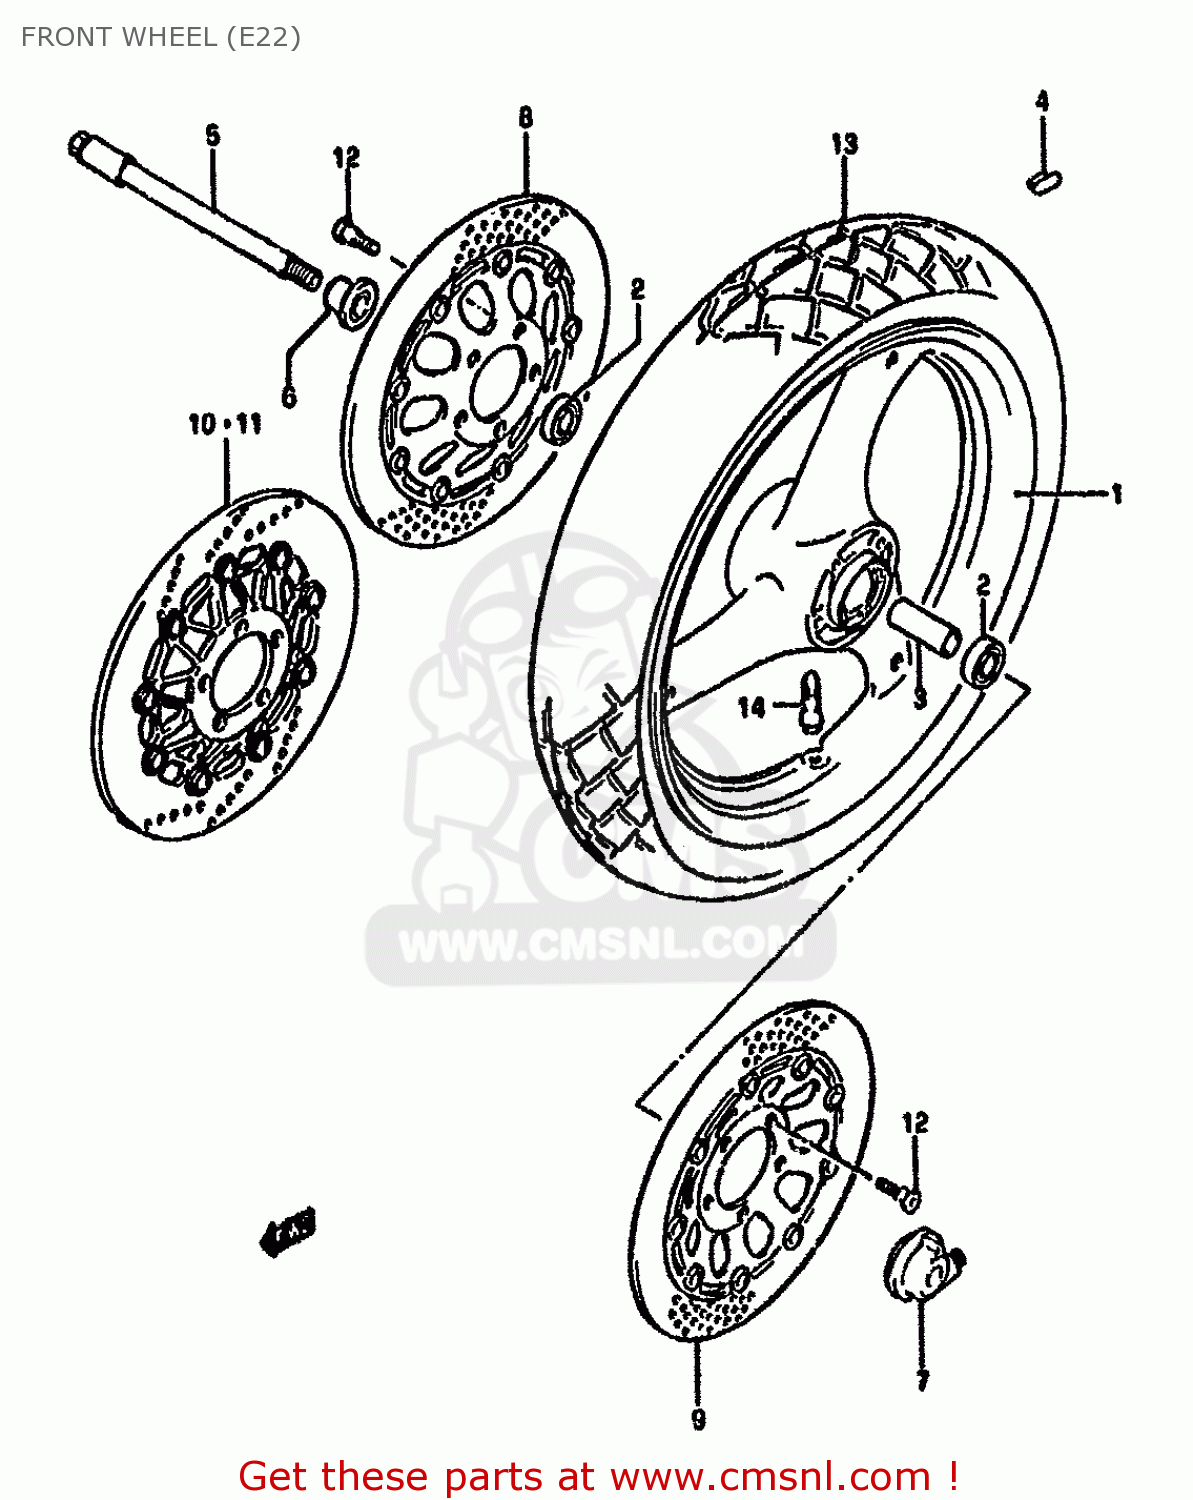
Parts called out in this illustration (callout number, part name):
1	WHEEL,FRONT (MT3.00X17) (GOLD)
2	BEARING
3	SPACER(17.5X22.5X73)
4	BALANCER,WHEEL
5	AXLE,FR
6	SPACER,FR AXLE,R
7	BOX ASSY,SPEEDOMETER GEAR
8	DISC,FR BRAKE,R
9	DISC,FRONT BRAKE LH
10	DISC,FR BRAKE,R
11	DISC,FR BRAKE,L
12	BOLT 8X33
13	TIRE,FR(110/70-17 54H)
14	VALVE ASSY,WHEEL RIM(TR412)
